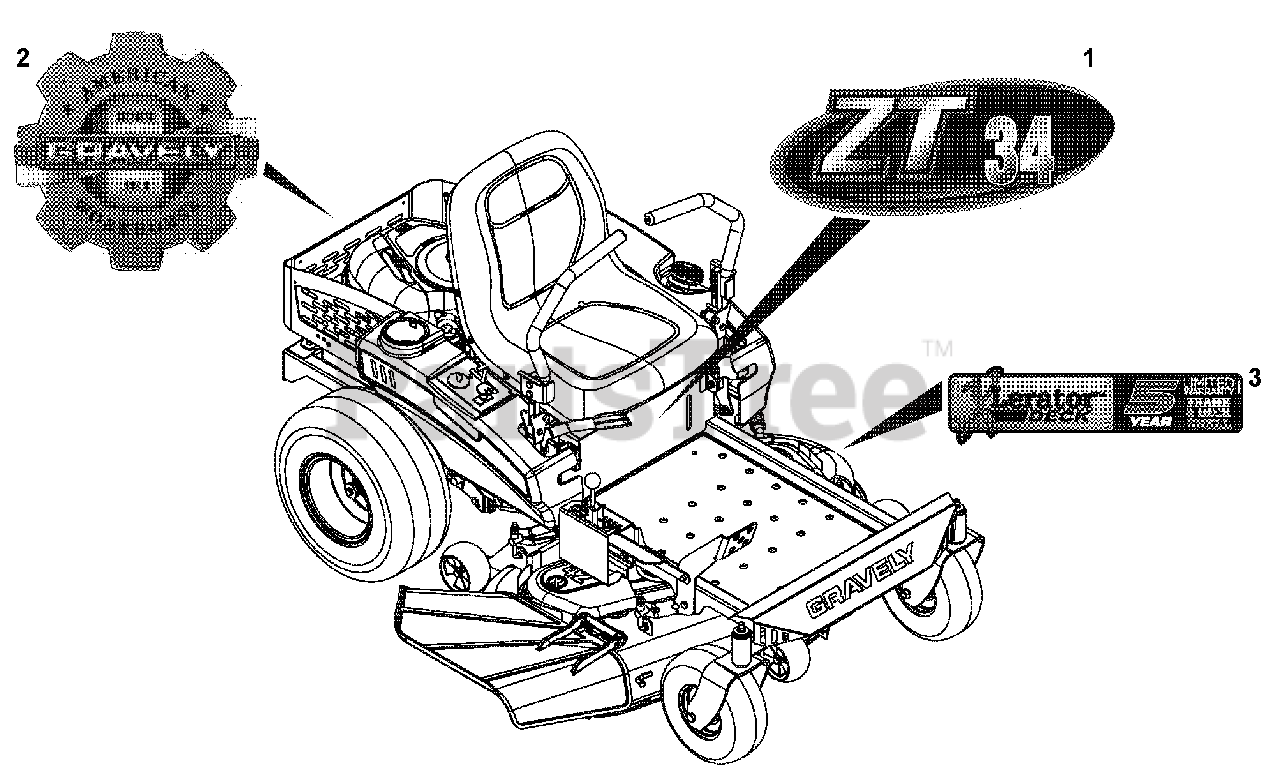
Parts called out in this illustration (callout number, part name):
1	Decal, ZT 34 (915327)
1	Decal, ZT 42 (915328)
2	Decal, Gravely Heritage, Large
3	Decal, Deck Warranty - Xcel
